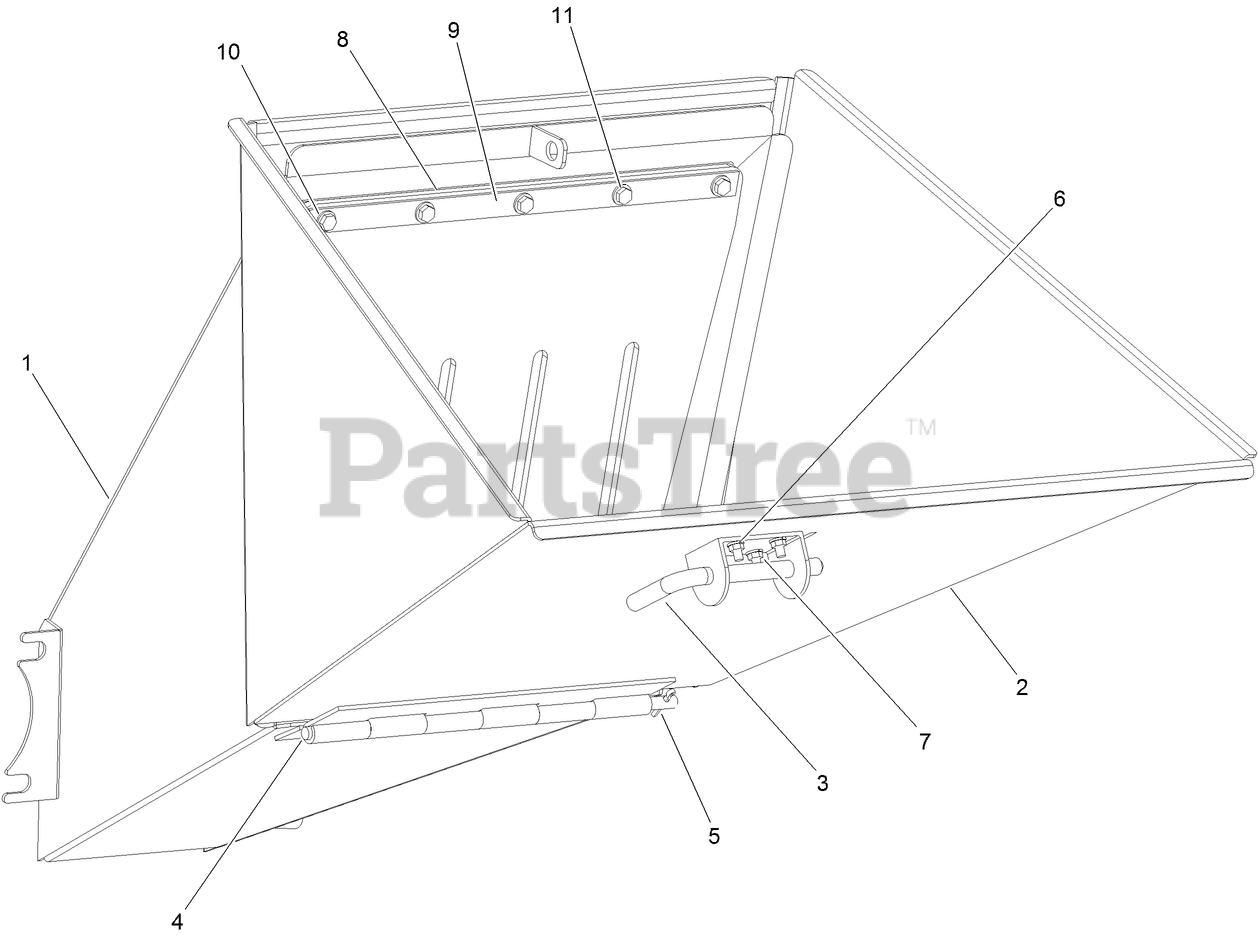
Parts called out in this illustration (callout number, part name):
1	FUNNEL ASM
2	FUNNEL DOOR ASM
3	PIN-LATCHING
4	ROD-HINGE
5	PIN-COTTER
6	WASHER-LOCK
7	NUT-HEX
8	FLAP-CHIPPER
9	ANGLE-FLAP
10	WASHER-FLAT
11	SCREW-HWH, THREAD ROLL
